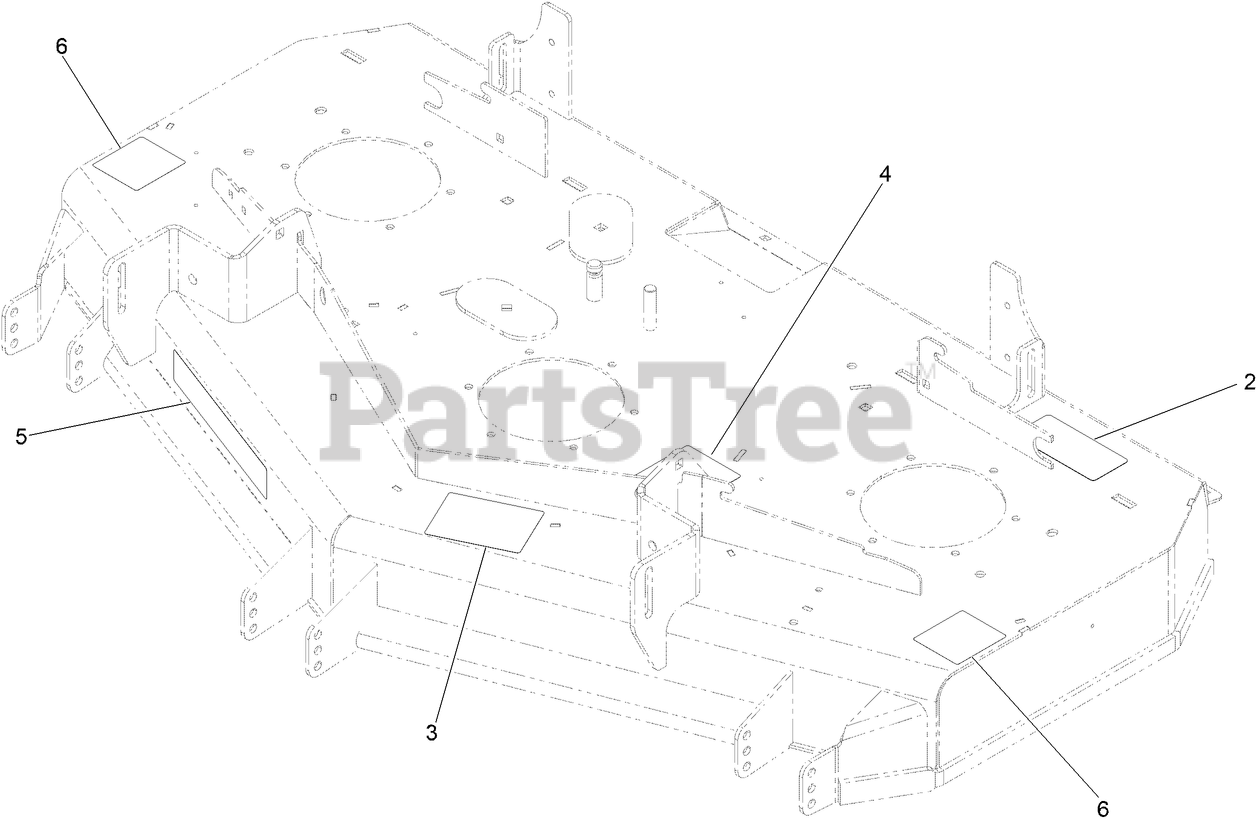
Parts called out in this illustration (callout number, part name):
2	DECAL-TORQUE, BLADE BOLT
3	DECAL-SCALP, ANTI
4	DECAL-ROUTING, BELT
6	DECAL-DANGER, THROWN OBJECT
